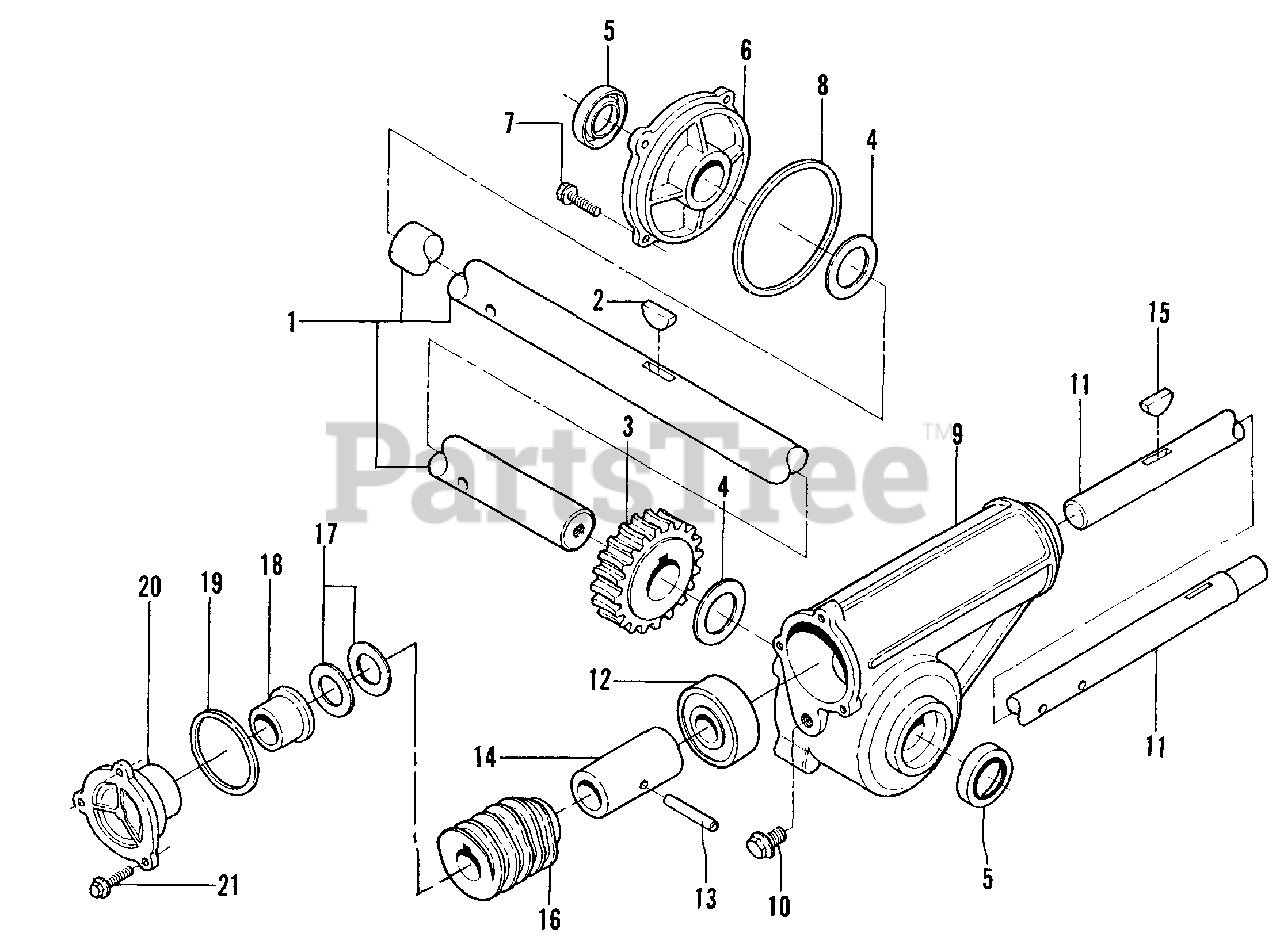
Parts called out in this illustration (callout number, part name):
1	SHAFT, Auger
2	KEY, Woodruff
3	GEAR, Worm
4	WASHER, Thrust
5	SEAL, Oil
6	COVER, Gear Case
7	SCREW, 1/4-20 x 3/4" Self-Tapping
8	O-RING (Case Cover)
9	CASE, Gear
10	SCREW, 3/8-16 x 1/2" Self-Tapping (Check Plug)
11	SHAFT, Impeller Fan
12	BEARING, Ball
13	PIN, 1/4 x 1-1/2" Roll
15	KEY, 3/16 x 7/8" Woodruff
16	GEAR, Rolled Worm
17	WASHER (Spacers)
18	BUSHING
19	O-RING (End Cap)
20	CAP, End
21	SCREW, #10-24 x 5/8" Self-Tapping
